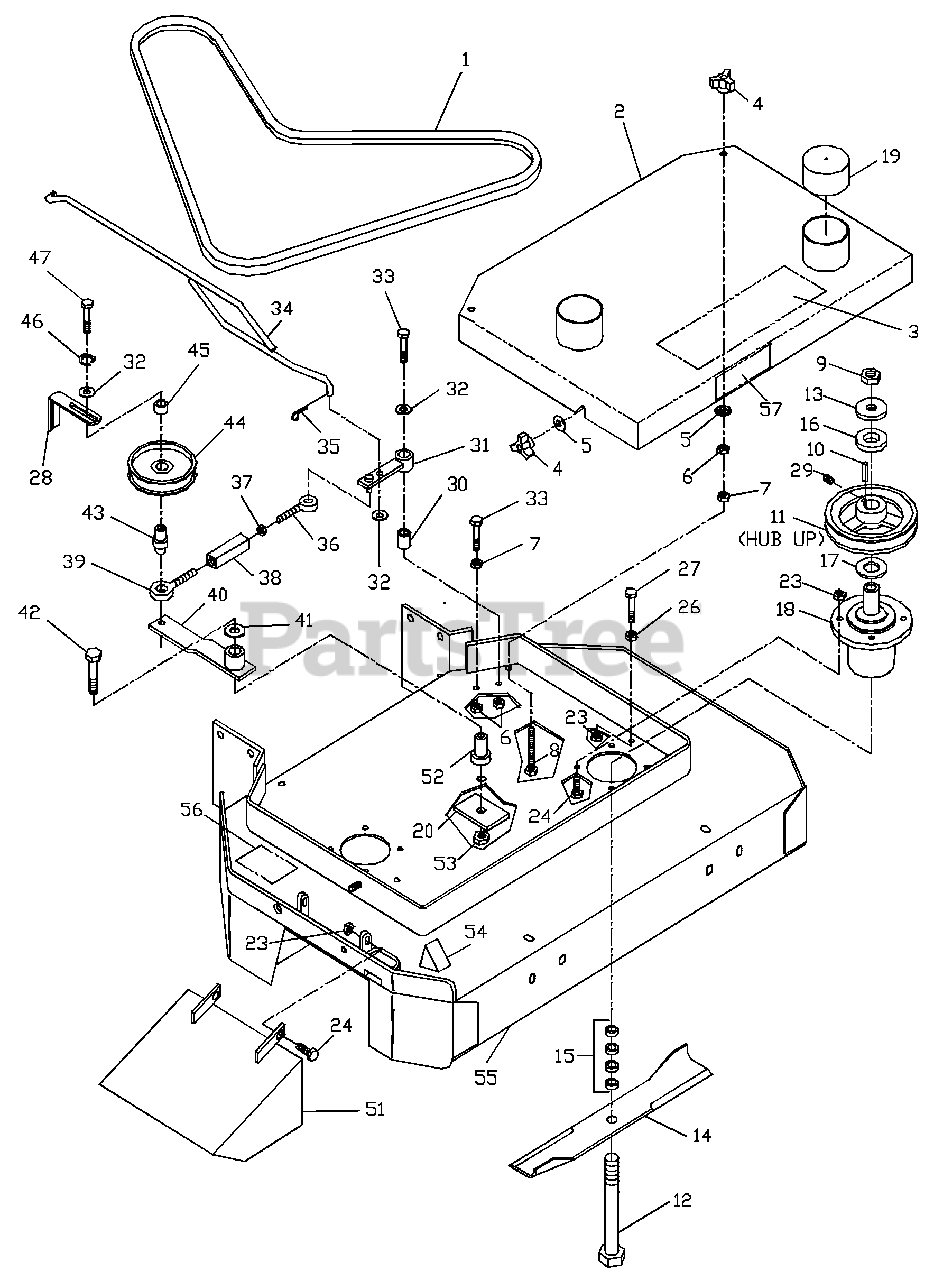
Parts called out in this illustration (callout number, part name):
1	36" DECK BELT
2	36" BELT SHIELD
3	DECAL, HUSQVARNA
4	THREE PRONG KNOB
5	3/8 SEALING WASHER
7	3/8C WHIZ NUT
8	TAPBOLT 3/8C X 4 1/2
10	KEY 1/4SQ. X 1 1/8
11	PULLEY W/SETSCREWS
12	HCS 5/8F X 8 1/2
13	SUPPORT WASHER
14	BLADE 18" (36)
15	BLADE SPACERS
17	MACH. BUSHING 10GA.
18	HOUSING ASM.
24	HCS 5/16C X 1
26	HFLN 5/16C
27	HCS 5/16C X 3
29	5/16 NYLOC SETSCREW
30	SLEEVE BUSHING
31	ENGAGEMENT ARM
32	FW 3/8 STD
33	HCS 3/8C X 2 1/4
35	#2 HAIRPIN
36	RT. HAND EYEBOLT
37	5/16C HEX NUT
38	TURNBUCKLE
39	LT. HAND EYEBOLT
41	FW 1/2 STD
42	HCS 1/2C X 2 3/4
43	EYEBOLT PIVOT
44	IDLER PULLEY
46	3/8 LOCK WASHER
47	HCS 3/8C X 2 1/2
51	DEFLECTOR CHUTE
52	IDLER SPINDLE
53	HLN 1/2C NYLOC
54	DECAL, CPSC
55	36" DECK W/DECALS
56	DECAL, DANGER
57	DECAL, NASCAR
